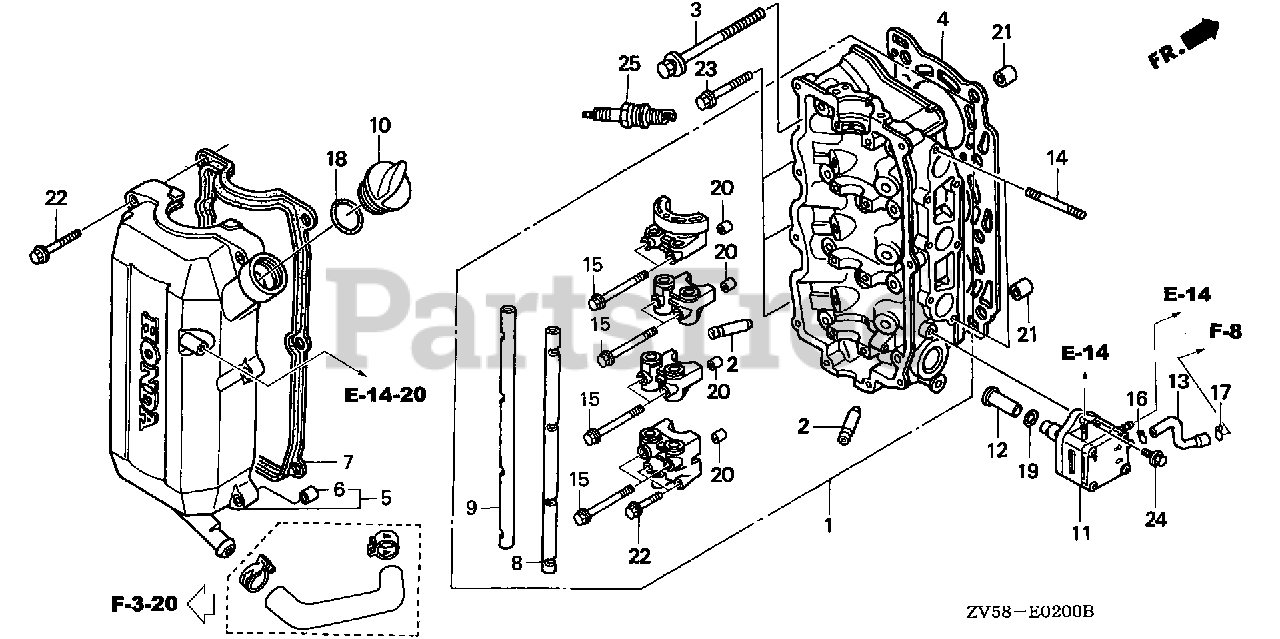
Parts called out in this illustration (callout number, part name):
1	CYLINDER HEAD ASSY. *NH8* (DARK GRAY)
2	GUIDE, VALVE (OVER SIZE)
3	BOLT-WASHER (10X85)
4	GASKET, CYLINDER HEAD
5	COVER, CYLINDER HEAD
6	COLLAR, HEAD COVER
7	GASKET, HEAD COVER
8	SHAFT, IN. ROCKER ARM
9	SHAFT, EX. ROCKER ARM
10	CAP, OIL (YELLOW)
11	PUMP ASSY., FUEL
11	PUMP ASSY., FUEL (MSDS)
12	LIFTER, FUEL PUMP
13	TUBE B, FUEL
14	BOLT, STUD (6X28)
15	BOLT, FLANGE (6X70)
16	CLIP, TUBE (B10)
17	CLIP, TUBE (B12)
18	O-RING (26X2.7)
19	O-RING (20.8X2.4)
20	PIN, DOWEL (8X14)
21	PIN A, DOWEL (12X16)
21	PIN, DOWEL (6X10)
22	BOLT, FLANGE (6X35)
23	BOLT, FLANGE (8X40)
24	BOLT, FLANGE (6X20)
25	SPARK PLUG (DR7EA) (NGK)
25	SPARK PLUG (X22ESR-U) (DENSO)
